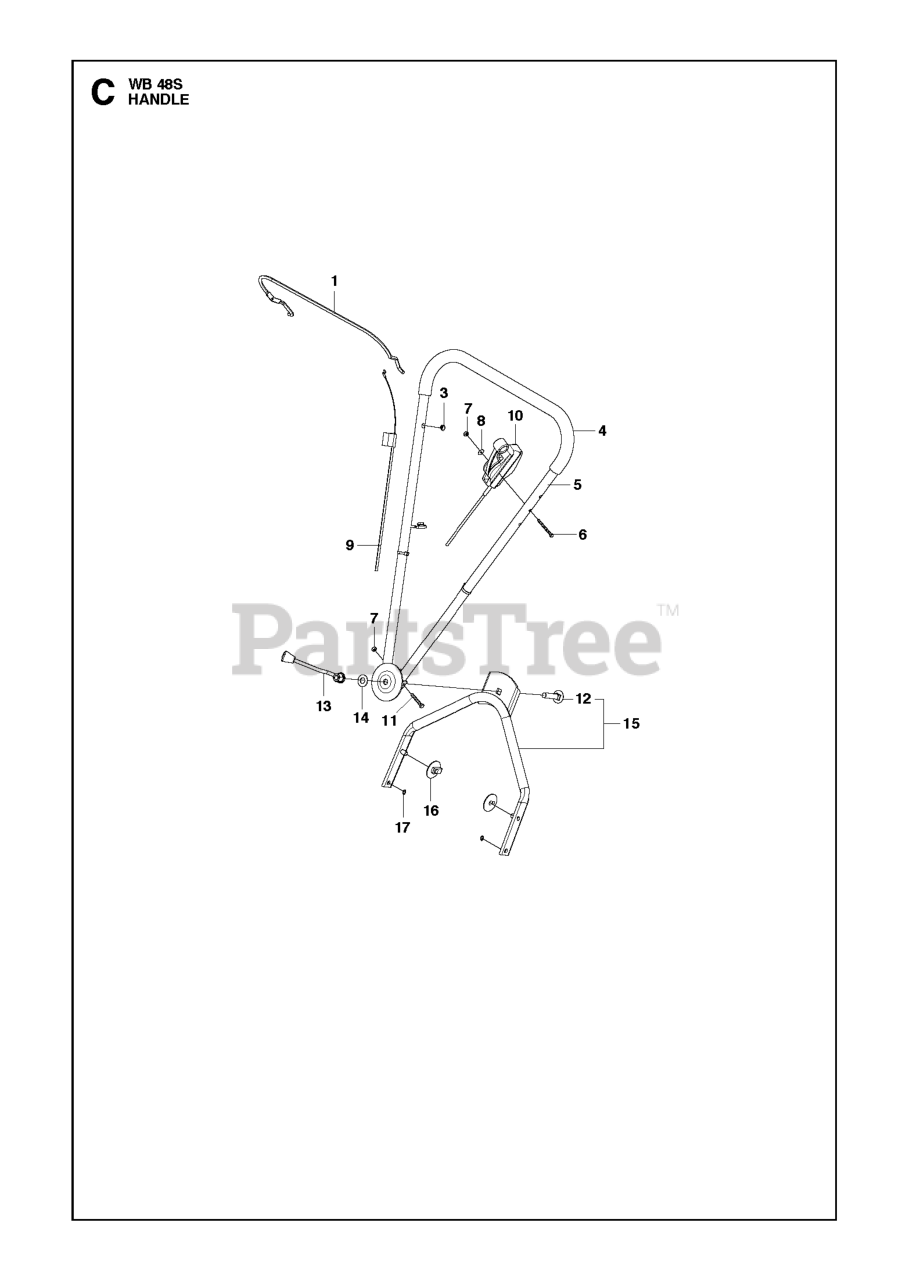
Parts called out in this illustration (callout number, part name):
6	SCREW M6X55
7	NUT FLANGE - M6
11	Hex Head Capscrew, M6 X 1.00 X 40MM
17	RETAINING RING SGA 10
